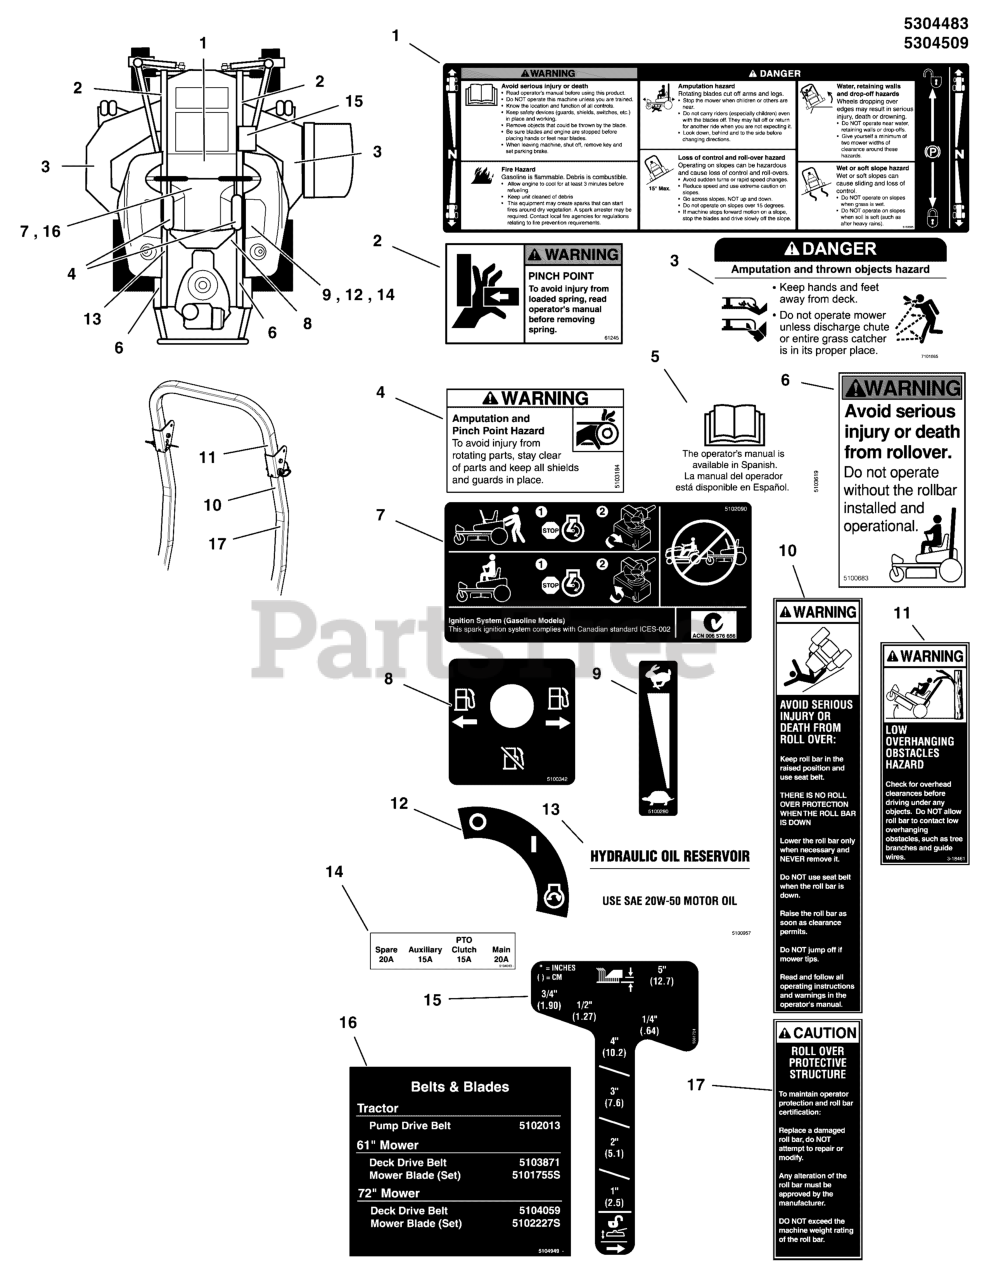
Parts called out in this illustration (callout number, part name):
1	DECAL, MAIN SAFETY
2	DECAL, Pinch Point
3	DECAL, DANGER DO NOT OPERATE W/O DEFLECT
4	DECAL, WARNING, HAND IN BELT, ENG ONLY
5	DECAL, MANUAL AVAILABLE IN SPANISH
6	DECAL, Warning, ROLL BAR
7	DECAL, TRANSAXLE RELEASE, S200XT
8	DECAL, FUEL VALVE
9	DECAL, Throttle Control
10	DECAL, WARNING, FOLDING ROLL BAR
11	DECAL, WARNING OVERHANG, ROPS (SV)
12	DECAL, IGNITION CONTROL
13	DECAL, HYDRAULIC OIL, SAE 20W50
14	DECAL, FUSE LOCATION, 20-15-15-20
15	DECAL, DECK HEIGHT, IS1500ZX
16	DECAL, BELT AND BLADE, F320, 61 & 72
17	DECAL, CAUTION, FOLDING ROLL BAR
